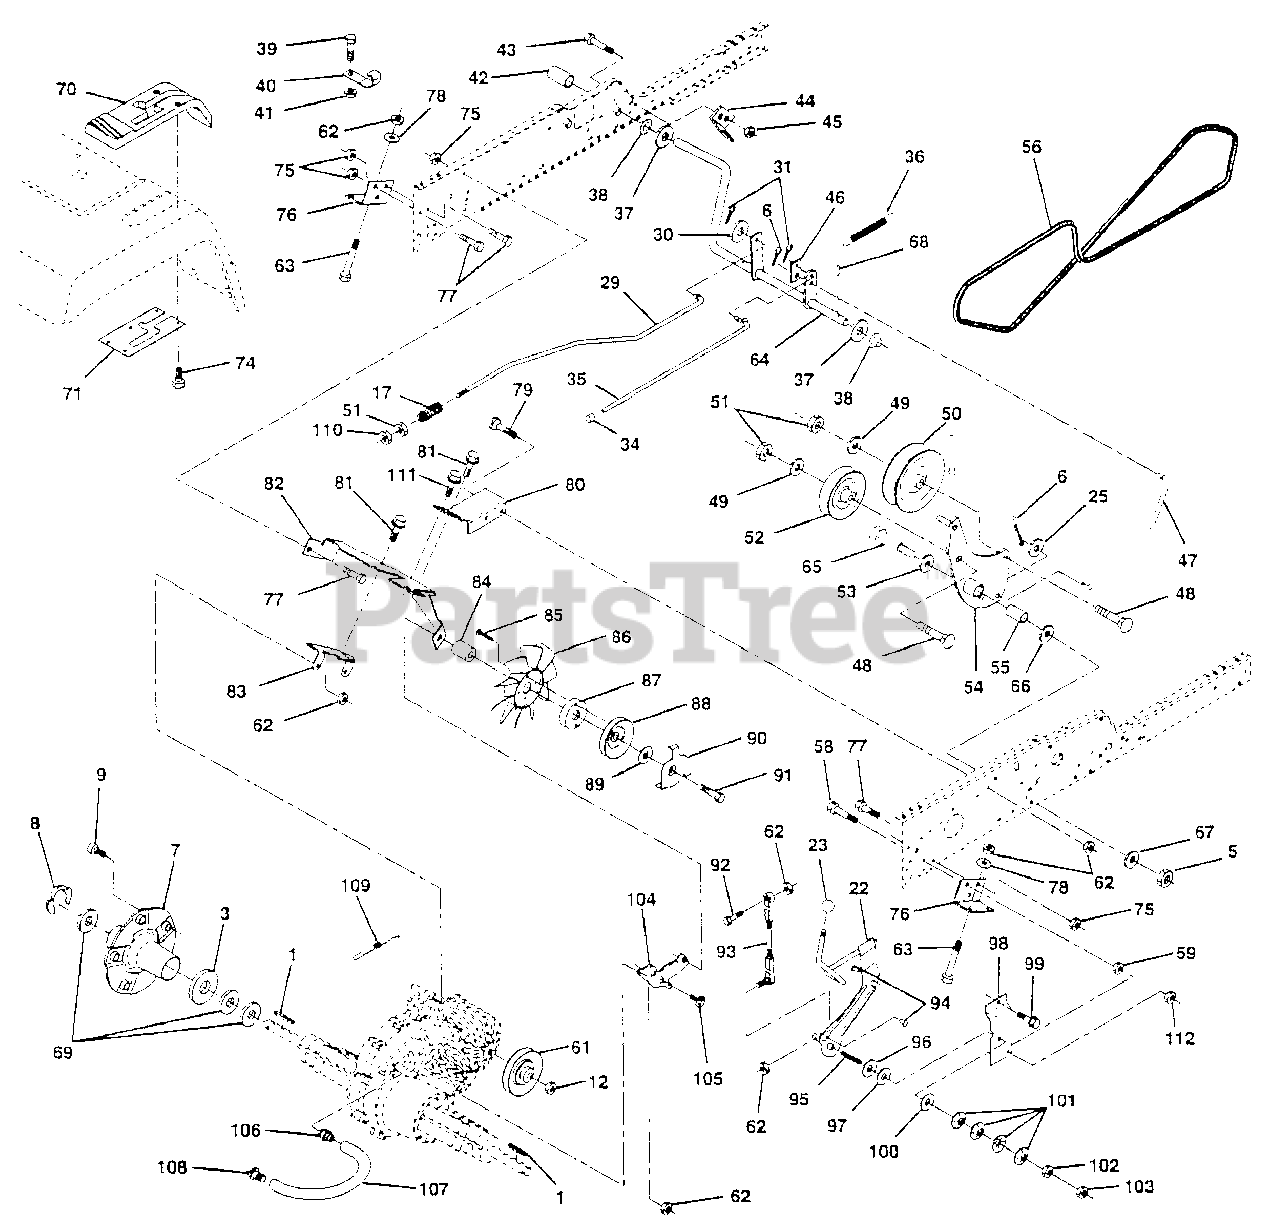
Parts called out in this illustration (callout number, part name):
1	Key 1/4 x 2.5
3	Washer Thrust Axle Harden
5	Nut Crownlock 3/8-16
6	Pin Cotter 1/8 x 3/4
7	Wheel Hub Asm.
12	Nut Hex Jam Toplock 1/2-20
17	Spring Rod Brake
22	Shaft Arm Asm
25	Washer 13/32 x 13/16 x 16 Ga.
30	Washer 13/32 x 1 x 14Ga
31	Pin Cotter 3/32 x 3/4
34	Cap Plunger
35	Rod Parking Brake
36	Spring Extension
37	Washer 25/32 x 1-1/4 x 16 Ga.
39	Screw Fin #10-24 x 1
40	Actuator Interlock Switch
41	Nut Lock #10-24
42	Cover Pedal
43	Bolt Hex Head 1/4-20 x 3/4
44	Bracket Interlock
45	Nut Lock W/Insert 1/4-20
46	Retainer Spring
47	Clutch Rod
48	Bolt Carriage 3/8-16 x 1-3/4 Gr. 5
49	Washer 13/32 x 7/8 x 13 Ga
50	Pulley Idler Flat
51	Nut Lock Hex 3/8-16
52	Pulley Idler Grooved
53	Washer Hartdened
54	Clutch Arm Asm
55	Bearing, Idler
58	Bolt Fin Hex 7/16-14 x 1-1/2
59	Nut Hex 7/16-14
61	Pulley Imput
62	Locknut Hex W/Washer Insert
63	Bolt Fin Hex 5/16-18 x 3
64	Shaft Asm Brake Parking Clutch
65	Bolt Shoulder
66	Washer Hardened
67	Washer 13/32 x 13/16 x 12 Ga
70	Console Hydro Fender
71	Plate Console Shift
74	Screw, Hex Wsh Hi-Lo 1/4-1/2
75	Nut Lock Hex 7/16
76	Bracket Transaxle
77	Bolt Fin Hex 7/16-14 x 1
78	Washer 11/32 x 3/4 x 12 Ga.
79	Bolt Carriage 5/16-18 x 5/8
80	Bracket Torque RH
81	Screw Thdrol 3/8-16 x 3/4
82	Bracket Mount Torque/Fan
83	Strap Torque Mid
85	Screw #10-24 x 1-1/4
86	Fan 7" Hydro
87	Adapter Fan
88	Pulley Idler
89	Washer 13/32 x 13/16 x 12 Ga.
90	Keeper Belt
91	Screw Thdrol 3/8-16 x 2-3/4
92	Bolt Fin Hex 5/16-18 x 1.75
93	Link Shift Asm
94	Fastner Christmas Tree
95	Screw Set 5/16-18 x 1.75
96	Washer Nickel Plated
97	Bearing Trust
98	Bracket Shift
99	Screw Thdrol 3/8-16 x 1-1/2
100	Washer Compression
101	Washer Bellviile
102	Nut Hex Nylok
103	Nut Hex Jam 5/16-18
104	Bracket Idler
105	Screw Tap 1/4-20 x 1/2
106	Fitting Vent Hose
109	Spring Return Brake
110	Nut, Hex Jam 3/8-16
111	Screw, Hinge
112	Nut, Crownlock 7/16-14
